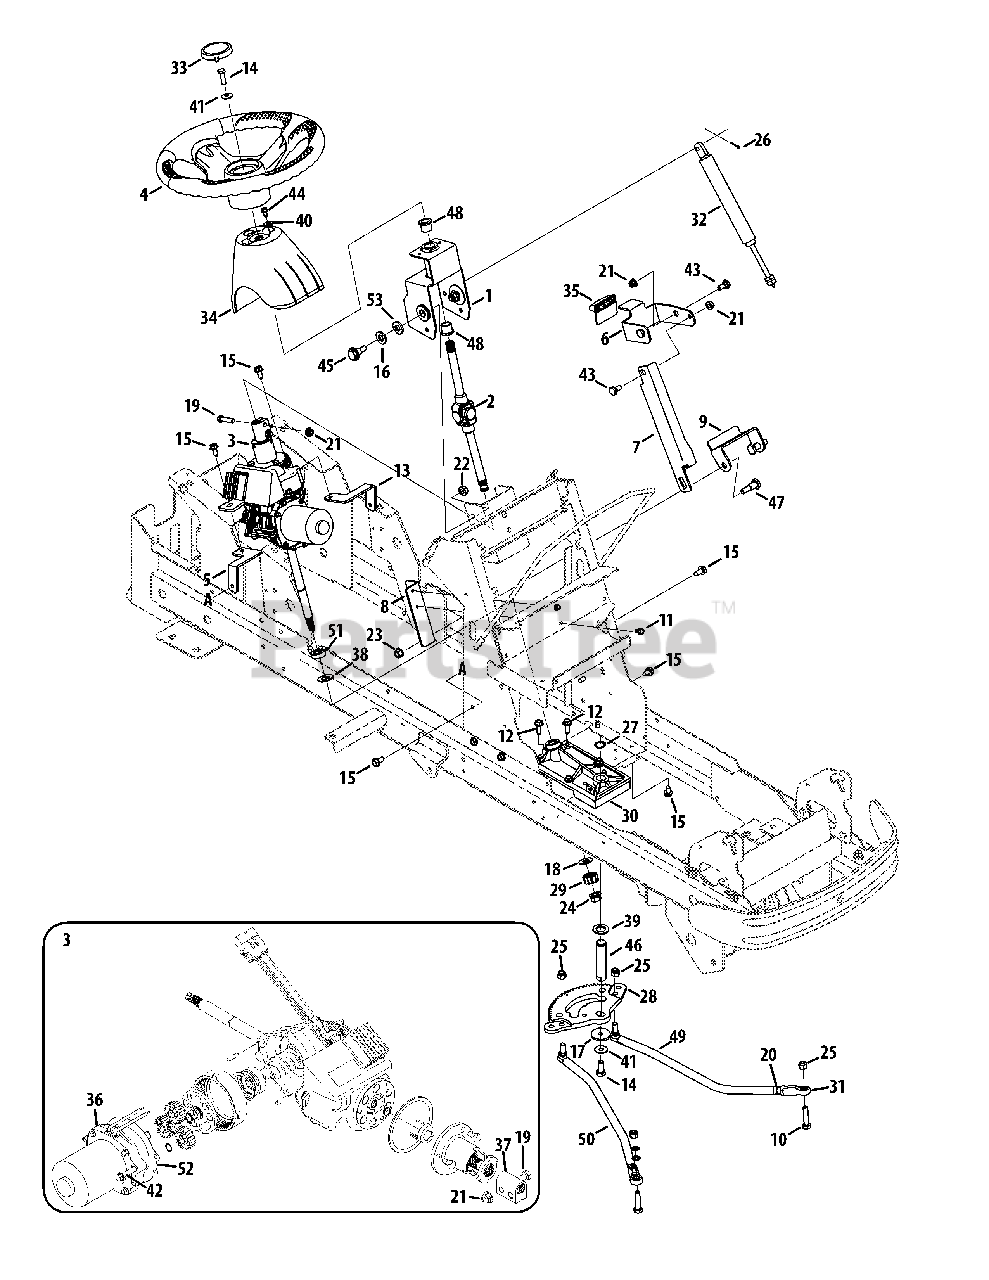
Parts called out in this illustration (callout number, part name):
1	Upper Steering Support Bracket
2	Power Steering Assembly
3	Transmission Assembly
4	Steering Wheel
5	Power Steering Mount Box, RH
6	Tilt Steering Lever Bracket
7	Tilt Steering Bracket
8	Tilt Steering Mount Bracket
9	Tilt Steering Pivot Bracket
10	Hex Screw, 3/8-24 x 2.00
11	Hex Washer Screw, 1/4-20 x .500
12	Hex Washer Screw, 5/16-18 x 1.000
13	Power Steering Mount Box, LH
14	Hex Lock Screw, 5/16-18 x 1.00
15	Hex Washer Screw, 5/16-18 x .750
16	Flat Washer, .510 x 1.14 x .040
17	Flat Washer, .340 x 1.50 x .150
18	Thrust Washer, .510 x 1.12 x .060
19	Hex Screw, 5/16-18 x 1.375
20	Jam Nut, 7/16-20
21	Flange Lock Nut, 5/16-18
22	Flange Lock Nut, 3/8-16
23	Flange Lock Nut, 3/8-16
24	Flange Lock Nut, 7/16-20
25	Hex Lock Nut, 3/8-24
26	Cotter Pin, 3/32 x .750
27	Snap Ring, .750
28	Segment Gear
29	Pinion Gear
30	Steering Housing
31	End Rod, 7/16-20 x 3/8
32	Locking Damper Cylinder
34	Dash Collar
35	Tilt Lever
36	Electric Motor
37	Steering Shaft Coupler
38	Flat Washer, .64 x 1.24 x .06
39	Flat Washer, .76 x 1.25 x .10
40	Flat Washer, .344 x .62 x .033
41	Bell Washer, .340 x .872 x .060
42	Hex Washer Screw, 1/4-20 x 1.250
43	Shoulder Screw, .435 x .178-5/16 x .56
44	Shoulder Screw, 1/4-20 x 0.500
45	Shoulder Bolt, 3/8-16 x .49 x .33
46	Steering Shaft
47	Shoulder Screw, 3/8-16 x .50 x .66
48	Flange Bearing, .630
49	LH Drag Link, 5/8
50	RH Drag Link, 5/8
51	Ring Spacer Hub
52	Motor Gasket
53	Flat Washer, .580 x 1.125 x .080
